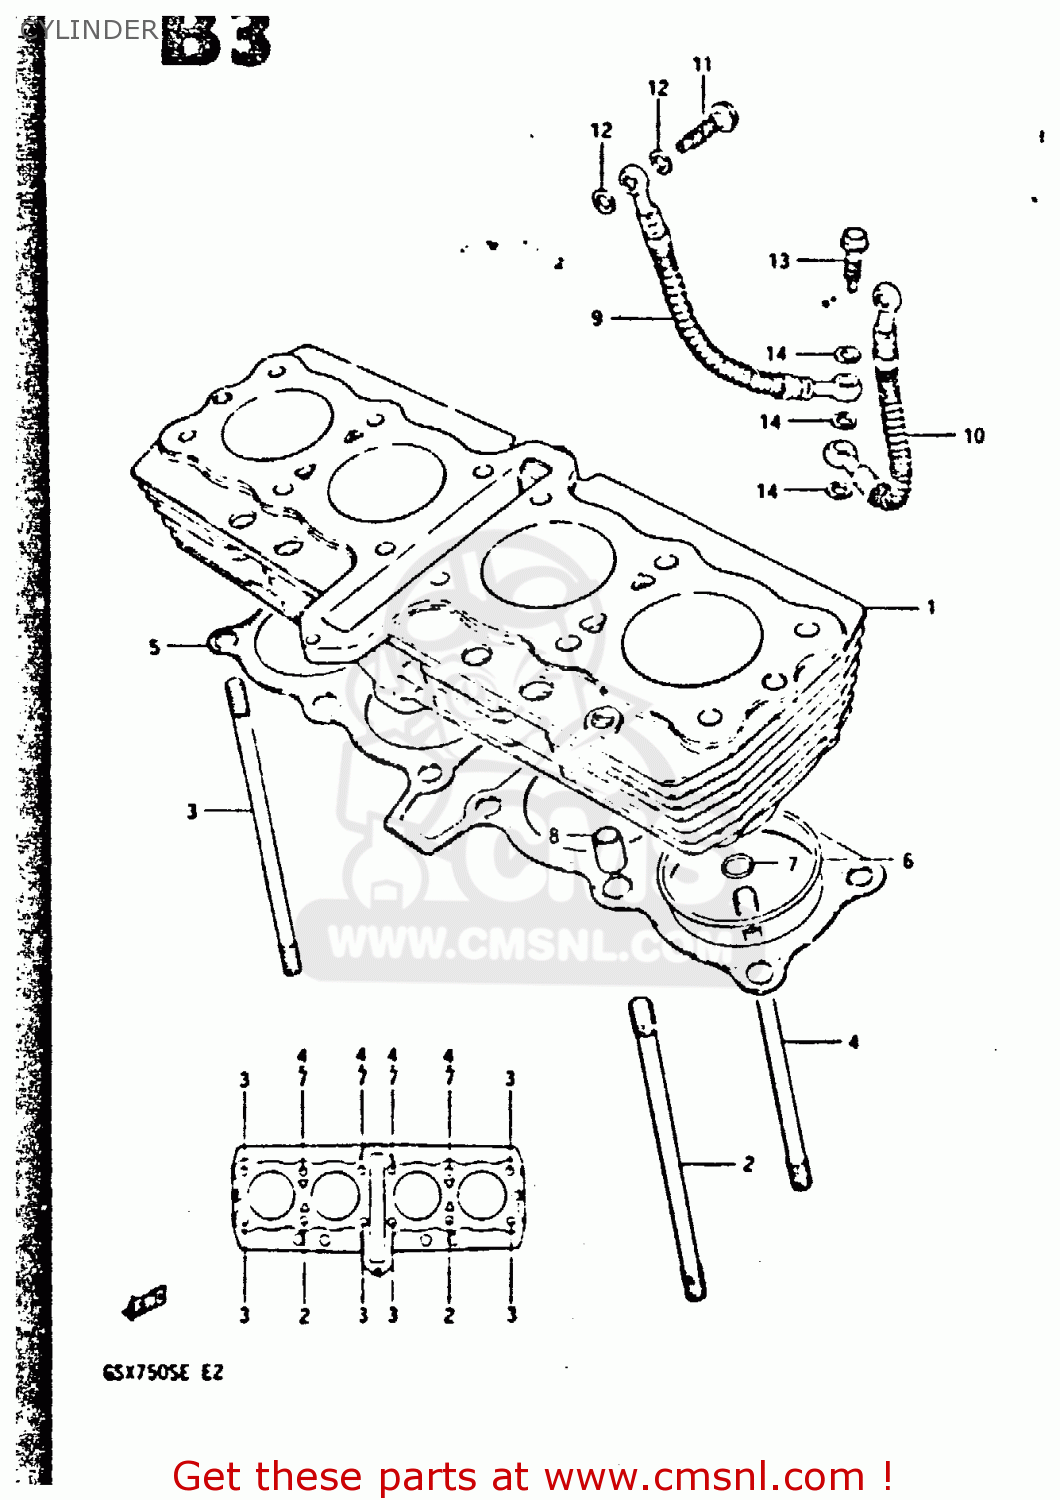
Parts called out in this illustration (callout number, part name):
1	CYLINDER
2	BOLT,STUD
3	STUD
4	STUD
5	GASKET,CYLINDER (NAS)
6	O RING(D:2,ID:70)
7	O RING(D:2.4,ID:11)
8	PIN
9	HOSE,OIL
10	HOSE,OIL
11	BOLT UNION
12	GASKET 8.2X14X1 (NAS)
13	BOLT,OIL PIPE
14	WASHER(10X15X1.5)
